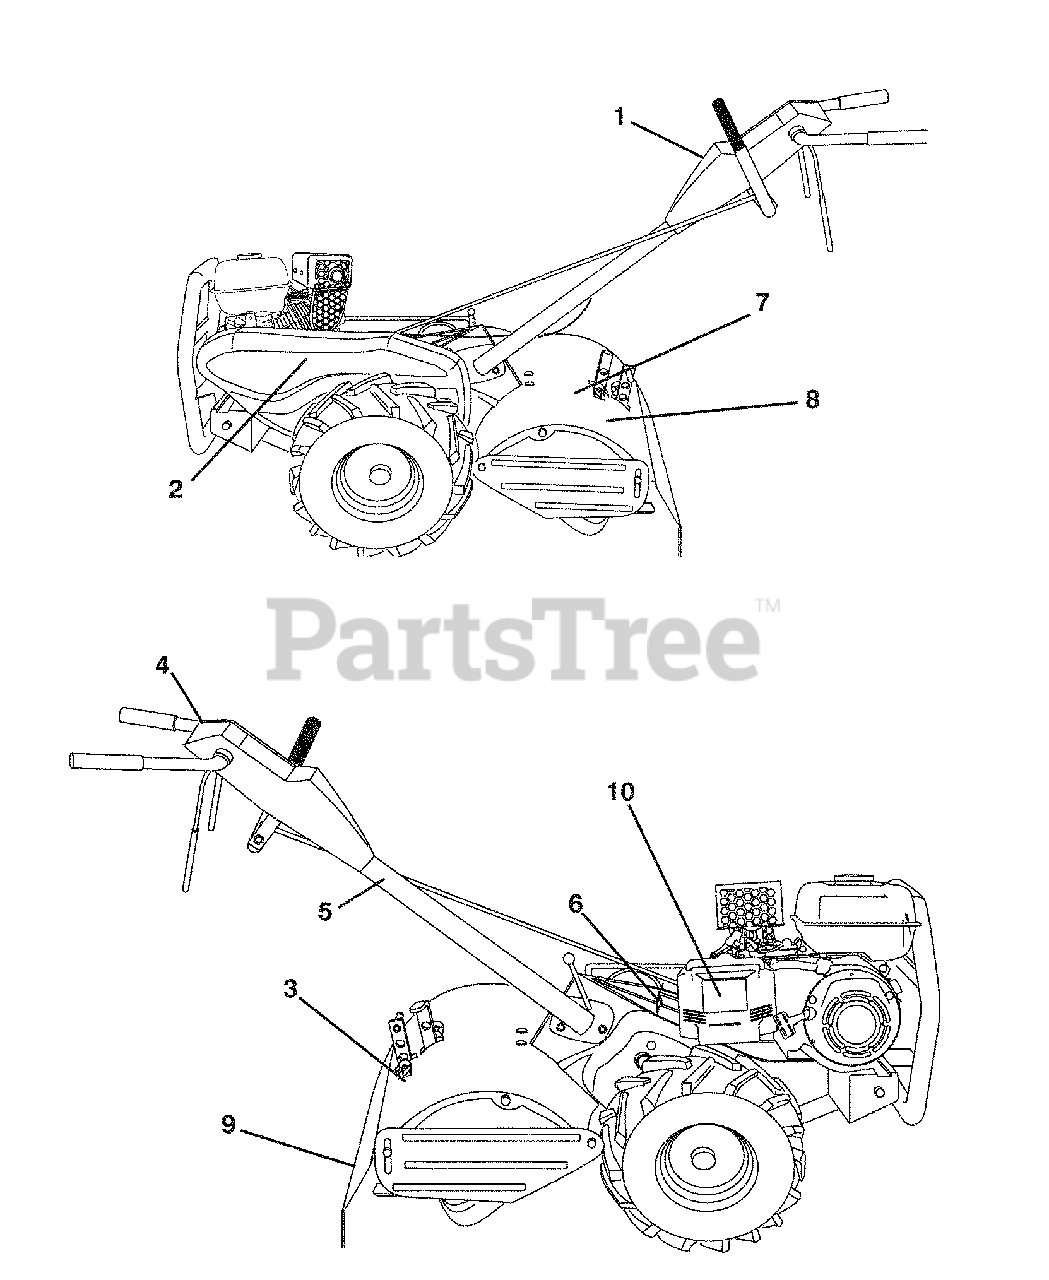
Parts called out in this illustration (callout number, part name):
1	Decal, Instruction, Tilling
2	Decal, Decal, Blt Grd
4	Decal, CNTRL PNL
5	Decal, Hand Placement
6	Decal, Shift Indicator
7	Decal, Shield
8	Decal, Forward
9	Decal, Warning, Rotating Tines
10	Decal, Air Cleaner
